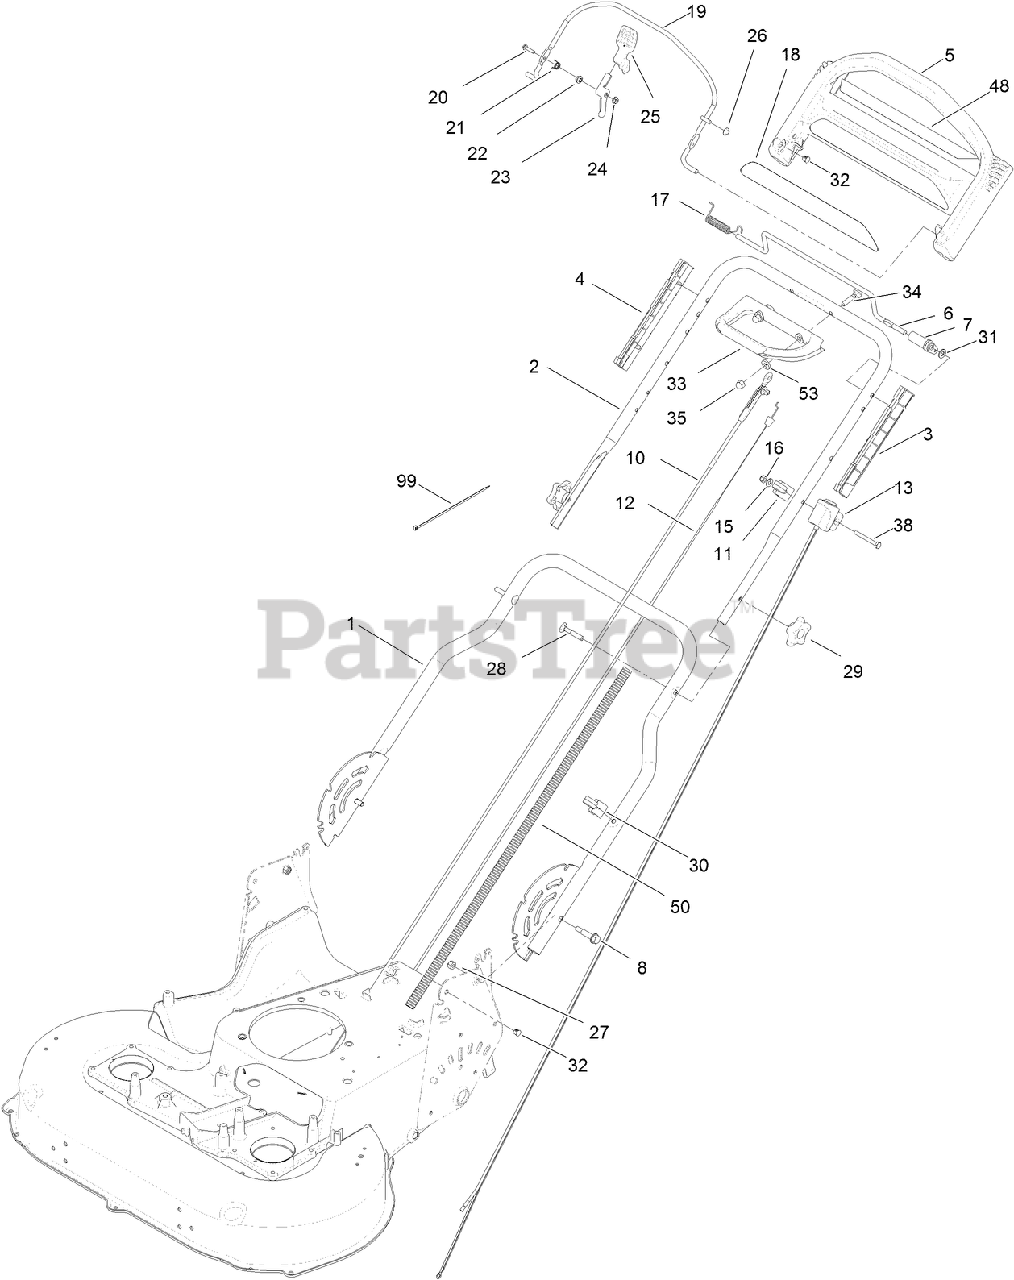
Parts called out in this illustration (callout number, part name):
1	HANDLE-LOWER
2	HANDLE-UPPER
3	GUIDE-LH
4	GUIDE-RH
5	HANDLE-CONTROL
7	LEVER-TRACTION
8	BOLT-SHOULDER, HHF
12	CABLE-TRACTION
13	SWITCH HOUSING ASM
15	WASHER-FLAT
16	NUT-LOCK, NI
19	BAIL-BRAKE
20	SCREW-HWH
21	SPRING-TORSION
22	SPACER
23	LEVER
24	NUT-LOCK, FLANGE
26	NUT-SPEED
27	NUT-LOCK, NI
28	SCREW-HANDLE
29	KNOB-HANDLE
30	GUIDE-CABLE
31	WASHER-PLAIN
32	PLUG-DOME
33	HANDLE-ASSIST, TRACTION
34	SCREW-HANDLE, LOCK
35	NUT-ACORN
38	SCREW-HH
48	DECAL-ASSIST, TRACTION
50	CONDUIT-CONVOLUTED
53	WASHER-PLAIN
99	TIE-CABLE
